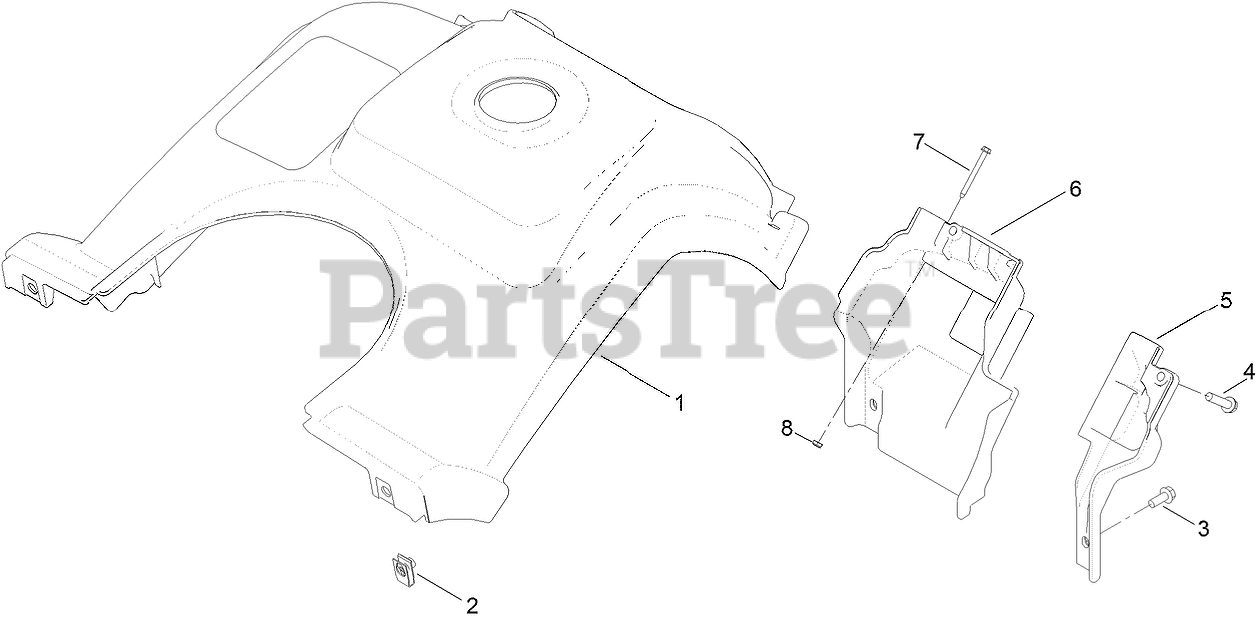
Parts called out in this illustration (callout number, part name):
1	SHROUD ASM
3	SCREW-HWH
4	SCREW-PLASTIC
5	SHROUD-LOWER, LH
6	SHROUD-LOWER, RH
7	SCREW-HWH
8	NUT-HEX
